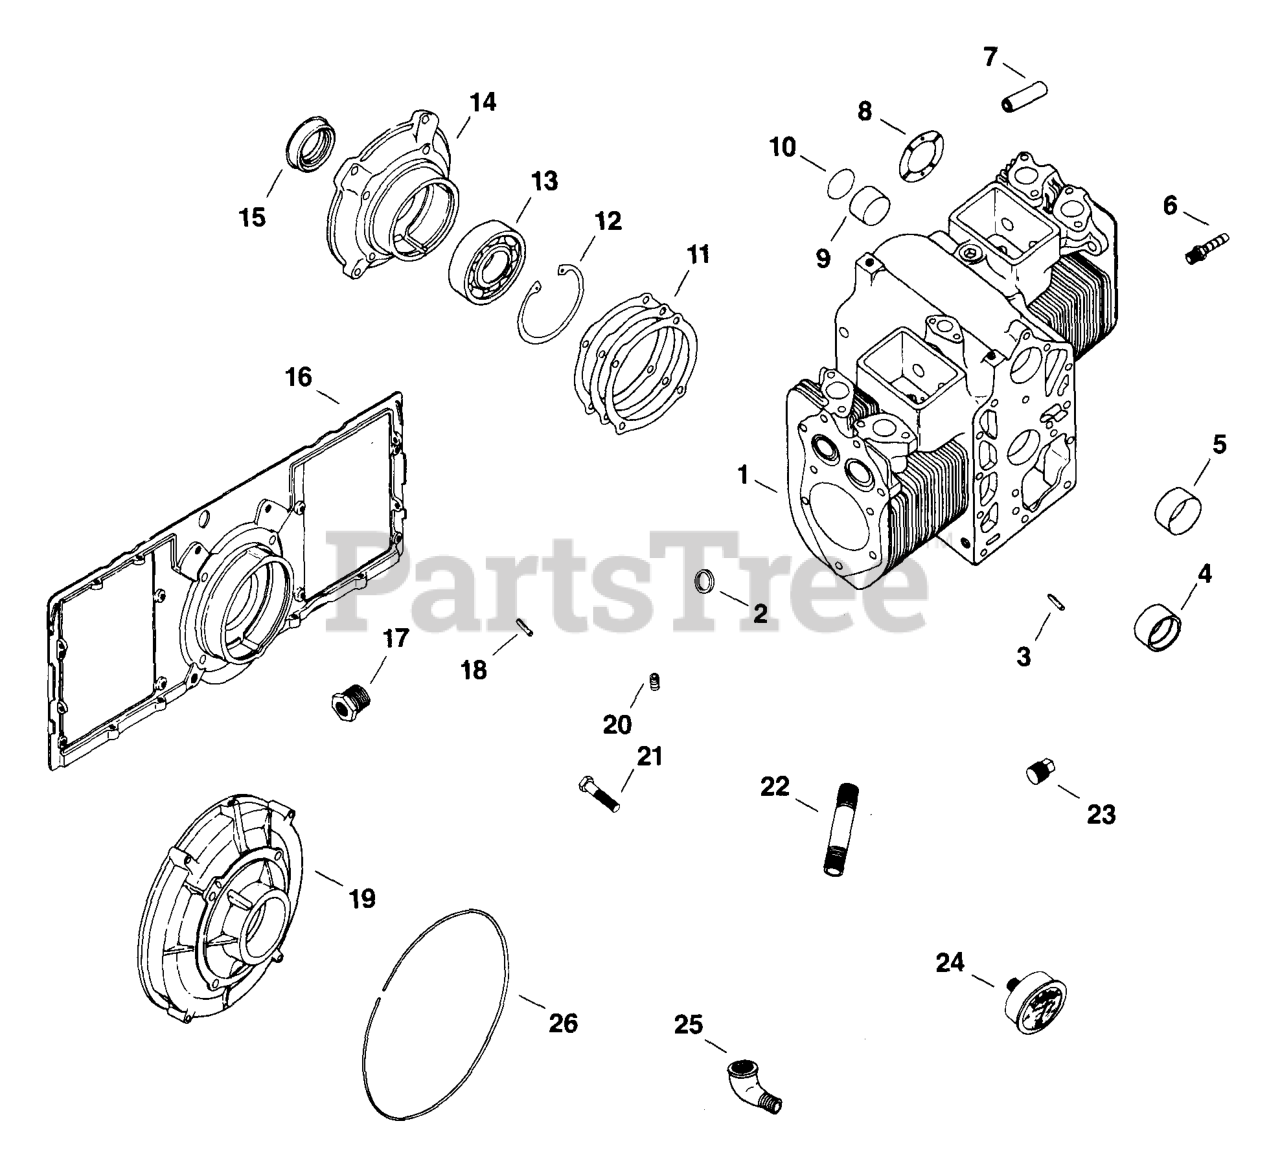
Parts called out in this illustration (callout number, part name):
1	BLOCK - USE 48 005 04
2	INSERT - DISCONTINUED
3	PIN-DISCONTINUED
4	BEARING - USE 48 030 06
4	BEARING - USE 48 030 07
4	BEARING, MAIN .020
5	BUSHING - USE 48 158 02
7	GUIDE, VALVE - DISCONTINUED
9	BUSHING - (#DSC)
12	RING (#DSC)
13	BEARING
14	PLATE - DISCONTINUED
20	PLUG, CTSK PIPE 1/8" USE 25 139 60-S
20	PLUG - DISCONTINUED
21	BOLT, HEX CAP USE 25 086 116-S
